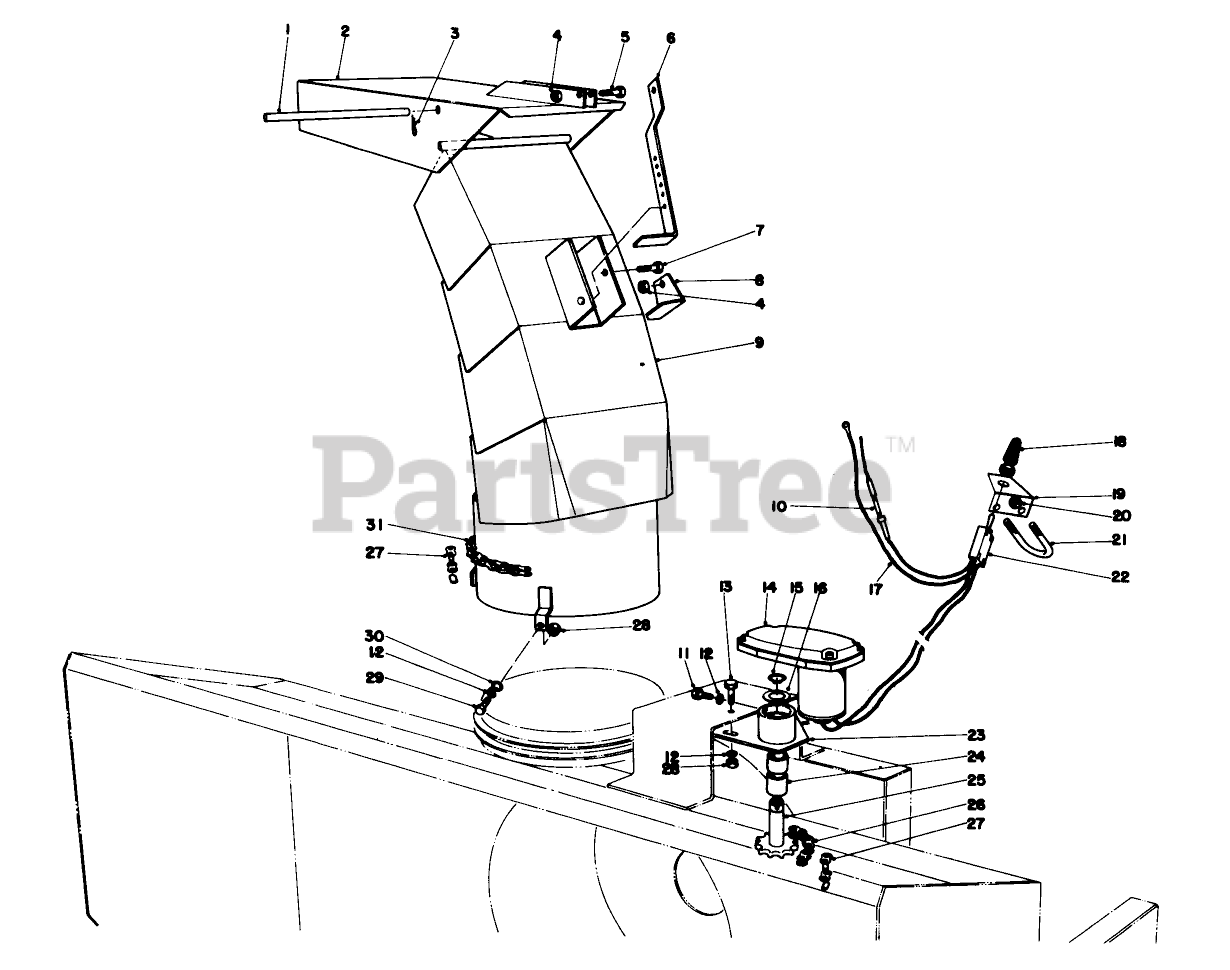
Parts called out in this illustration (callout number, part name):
1	Hinge Rod
2	Deflector
3	PIN-COTTER, HAIR
4	NUT-HEX
5	SCREW-HH
6	Deflector Adjusting Handle
7	Capscrew
8	Adjustor Lock
9	Chute
10	Fuse 20 Amp
11	SCREW-HH
12	WASHER-LOCK
13	SCREW-HH
14	Motor & Gear Box Assembly
15	Ring-Snap
16	WASHER
17	Wiring Harness
18	Switch Boot
19	Electrical Switch Bracket
20	NUT-HEX
21	CLAMP
22	Electrical Toggle Switch
23	Actuator Mount
24	BUSHING
25	Drive Shaft
26	Chain Chute Actuator
27	LINK-CHAIN
28	NUT-HEX
29	SCREW-HH
30	WASHER-FLAT
31	Chute Rotator Chain
